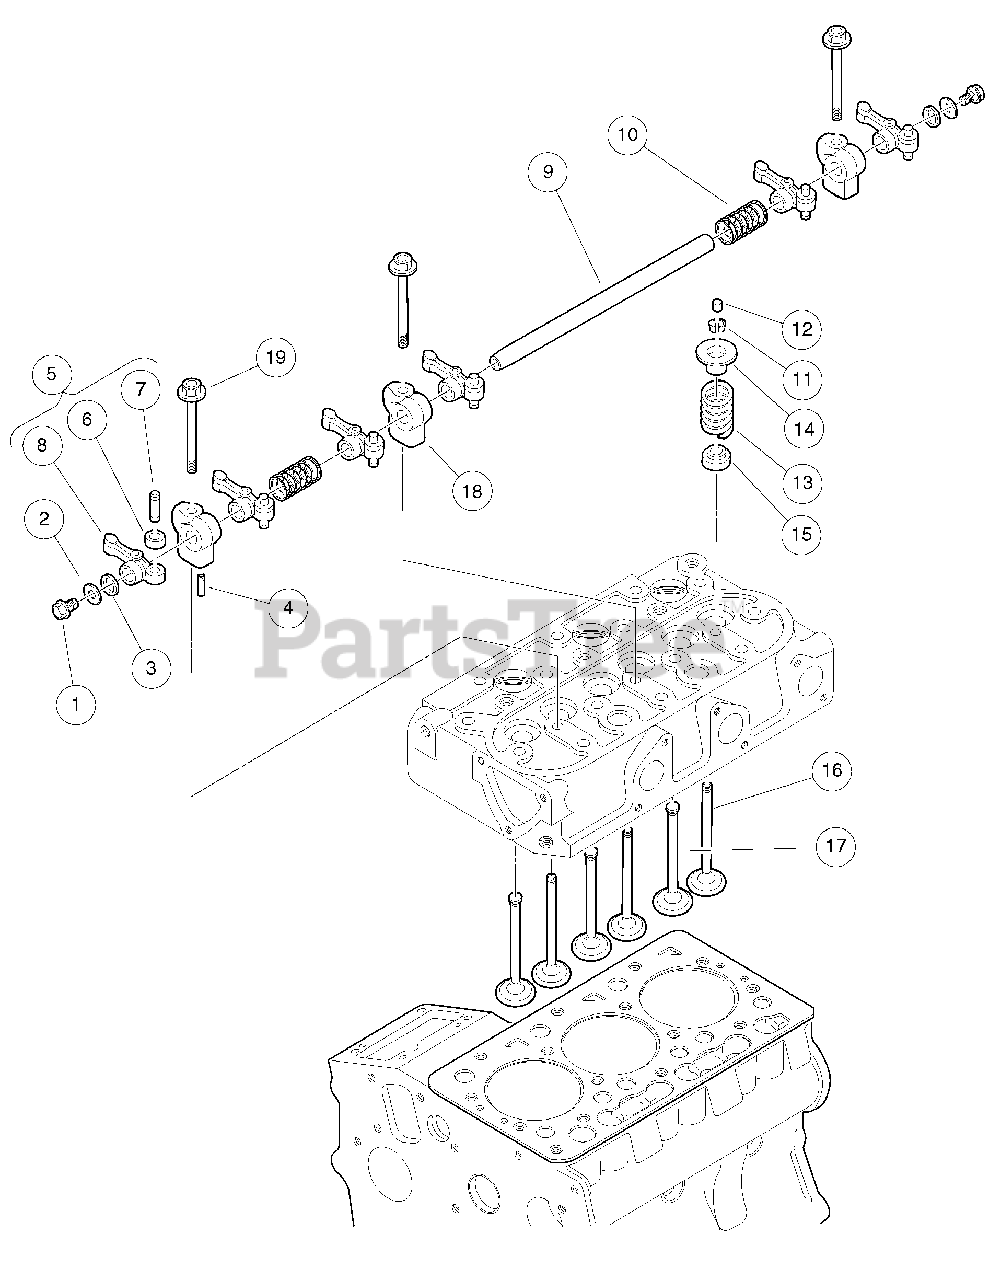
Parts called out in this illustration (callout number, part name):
1	Bolt, M6 X 1 X 8
2	Washer, D722, Plain, Rocker
3	Washer, Rocker Arm
4	Pin, Spring, D722, Rocker
5	Assy Rocker Arm
7	Screw-Adjusting
8	Arm, Rocker
9	Shaft, Rocker Arm
10	Spring, Rocker Arm
11	Collet, Valve Spring, Set
12	Cap, Valve, D722
13	Spring, Valve
14	Retainer, Spring
15	Seal, Valve Stem
16	Valve, Exhaust
17	Valve, Inlet
18	Bracket, Rocker Arm, D722 Closed-Breather
19	Bolt, Rocker Arm
